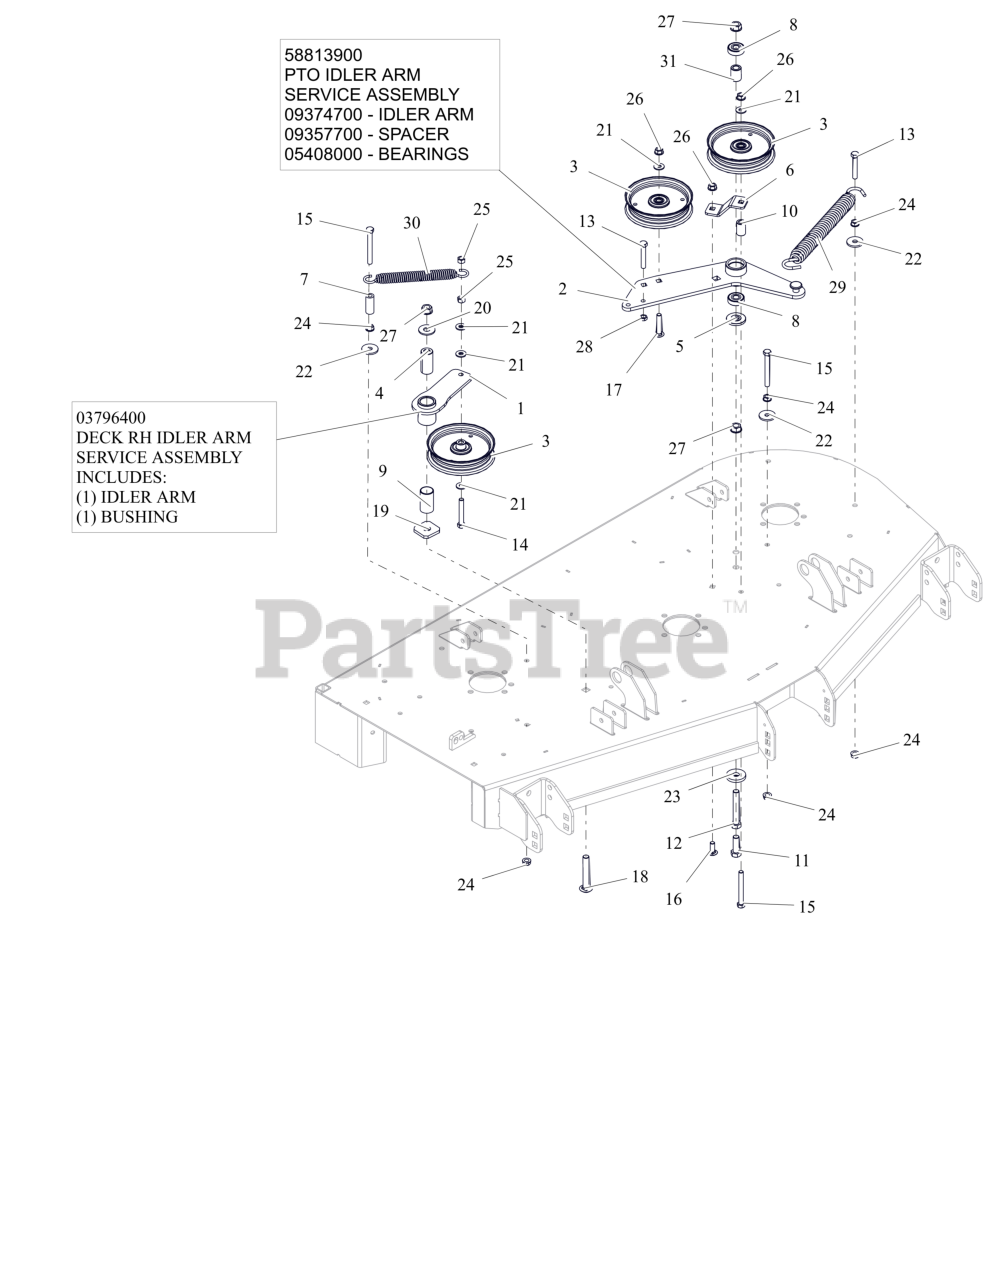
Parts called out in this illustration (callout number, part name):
1	WMT, IDLER ARM - BLACK
1	ASM, IDLER ARM (DECK)
2	WLDMT, IDLER ARM PT660
2	PTO IDLER ARM
3	IDLER- FLAT - 5.00" X .75"
4	BSHG, SPCR .502X.997X2.03 PM
5	SPACER, IDLER ARM
6	PTO FIXED IDLER MTG BRKT-ORG
7	HOSE, .38 X 1.65
8	BRG-BALL .500X1.38X.437
9	BSHG, 1.00X1.125X1.937
10	BUSHING, SLV .380X.750X1.190
11	BLT,HEX .50-13X1.50 G5 ZCC
12	BLT,HEX .50-13X3.25 G5 ZCC
13	BLT,HEX .38-16X2.25 G5 ZCC
14	BLT, HEX .38-16X2.50 G5 ZCC
15	BLT, HEX .38-16X3.25 G5 ZCC
16	BLT,RHSSN .38-16X1.00 G5 ZCC
17	BLT,RHSSN.375-16X2.00 G5 ZCC
18	BTL,RHSSN .500-13 X 3.25 G5 ZCC
19	WSHR-FLT .640X1.75X.250
20	WSHR,FLT .563X1.375X.109 ZCC
21	WSHR,FLT .375X.875X.083 ZCC
22	WSHR,FLT .406X1.375X.135 ZCC
23	WSHR-FL-STL 0.557X1.625X0.25 ZCC
24	NUT, SPNLK-FLG .38-16 G5 ZCC
25	NUT-LK-CTR .38-16 ZC120
26	NUT-LK-CTR-FLG .375-16 GF ZCC
27	NUT-LK-CTR-FLG .500-13 GG ZCC
28	NUT-JAM .375-16 G2 ZCC
29	SPRING, EXTENSION
30	SPRING- EXTENSION
31	SPACER .510 X .867 X 1.1485
